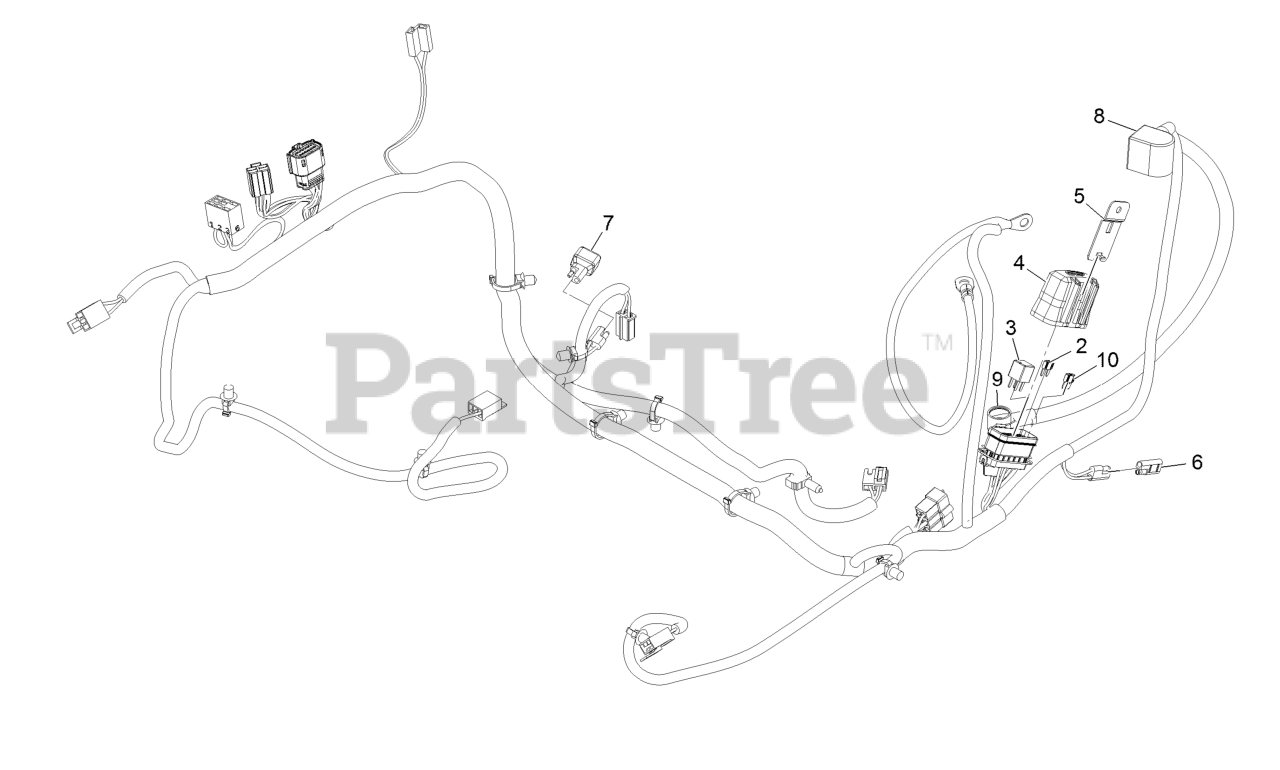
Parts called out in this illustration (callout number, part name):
2	Fuse-Mini Blade, 20 Amp
3	Relay-Micro
4	Cover-Block, Fuse
5	Clip-Mounting
6	Cap-Plug
8	Insulator-Battery
9	Insulator-Solenoid
10	Fuse-Mini Blade, 15 Amp
